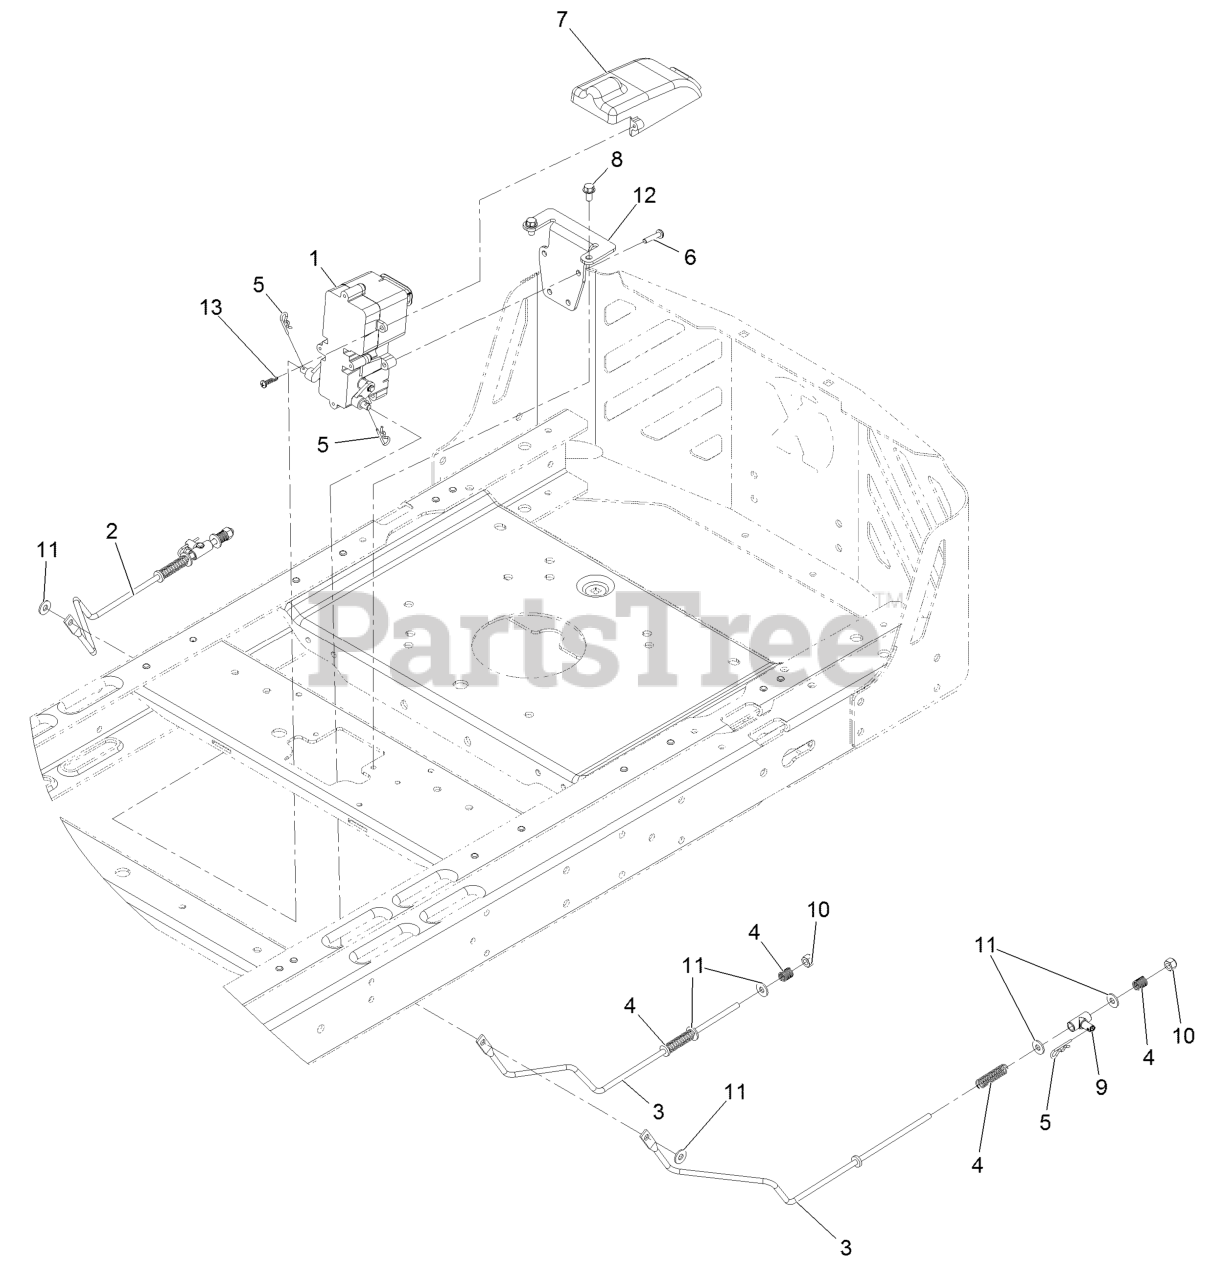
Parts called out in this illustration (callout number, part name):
2	ROD-BRAKE, RH
3	ROD-BRAKE, LH
4	SPRING-COMPRESSION
6	SCREW-PPH
7	COVER-CONNECTOR
8	SCREW-HWH
9	MOUNT-PIVOT
10	NUT-LOCK, NI
12	BRACKET-MOUNT, BRAKE
13	SCREW-PPH
